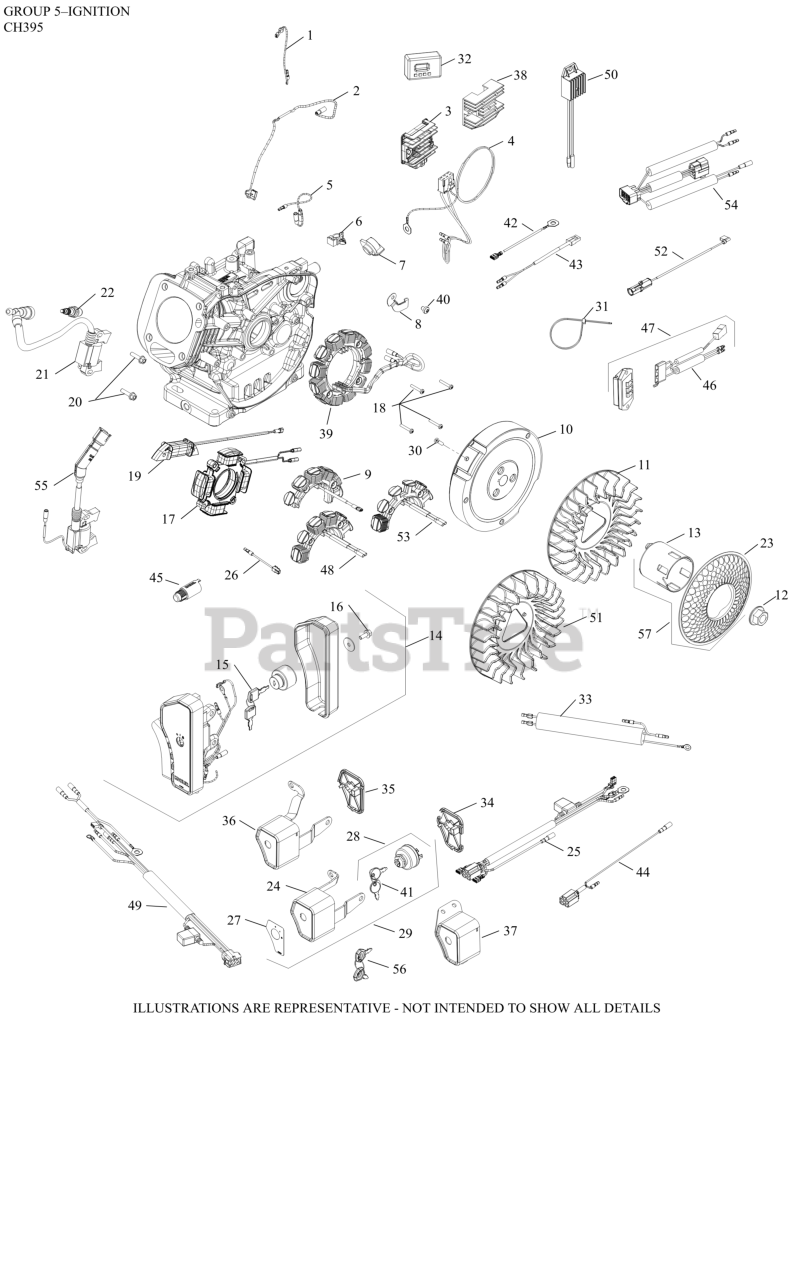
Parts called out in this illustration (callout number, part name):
2	LEAD, GROUND TO KILL
4	HARNESS, REGULATOR WIRING ASSY
8	BRACKET, STATOR WIRE
9	STATOR ASSEMBLY, 10A
10	FLYWHEEL ASSY ELECTRIC START (CH395)
11	FAN, FLYWHEEL
12	NUT, FLYWHEEL
13	CUP, STARTER DRIVE
18	SCREW, STATOR MOUNTING
20	SCREW, M6 X 25-(#25086436S)
21	MODULE, SPARK PLUG ASSY
22	SPARK PLUG
24	KIT, KEYBOX HOUSING ASSEMBLY
25	HARNESS, WIRING ASSEMBLY (10 AMP)
27	LABEL, KEY BOX
28	SWITCH, KEY ASSEMBLY
29	KIT, KEY BOX ASSEMBLY
34	COVER, KEY BOX
38	REGULATOR, 10 AMP
40	SCREW, COIL BRACKET
